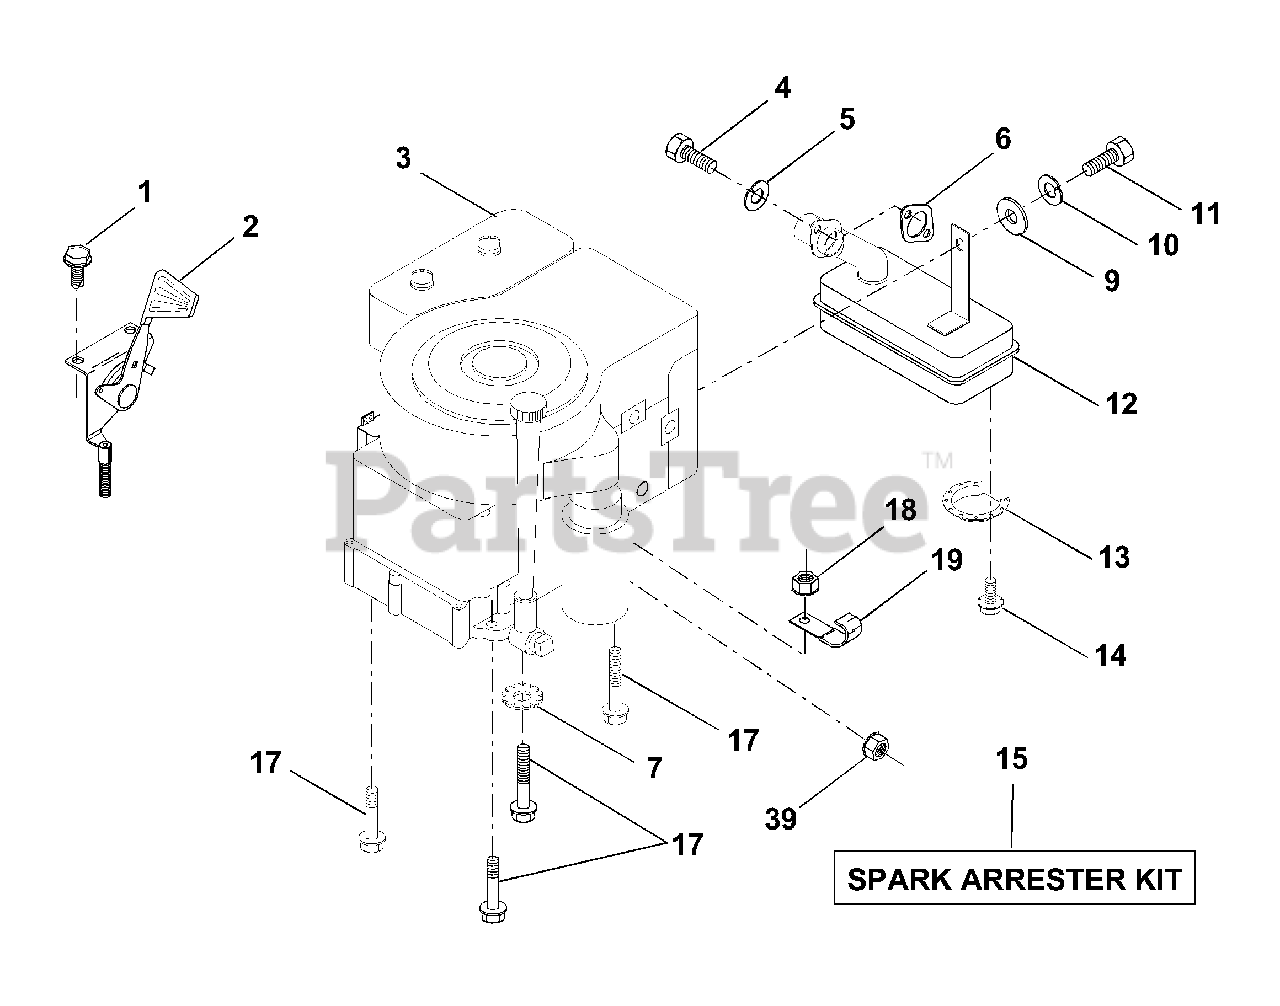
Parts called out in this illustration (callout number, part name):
1	Screw, Hex Thd. Cut 1/4-20 x 1/2
2	Control, Throttle
3	Engine, Briggs and Stratton Model No. 282707
4	Screw, Hex, Cap 5/16-18 x 3/4
5	Washer, Lock Heavy Helical Spring 5/16
6	Gasket, Exhaust
7	Washer, Lock Ext. Tooth 3/8
9	Washer 5/16 x 3/4 x 16
10	Washer, Lock Hvy Hlcl Spring 1/4
11	Bolt, Hex Fin.
13	Deflector, Muffler
14	Screw, Spiderloc Hex Hd #8 x 1/2 AB
15	Arrester, Spark
17	Screw, Hex Washer Head, Thdrol. 3/8-16 x 1-1/2
18	Screw Thdrol. 3/8-16
19	Clip Line Fuel
39	Nut, Keps Hex 1/4-20
